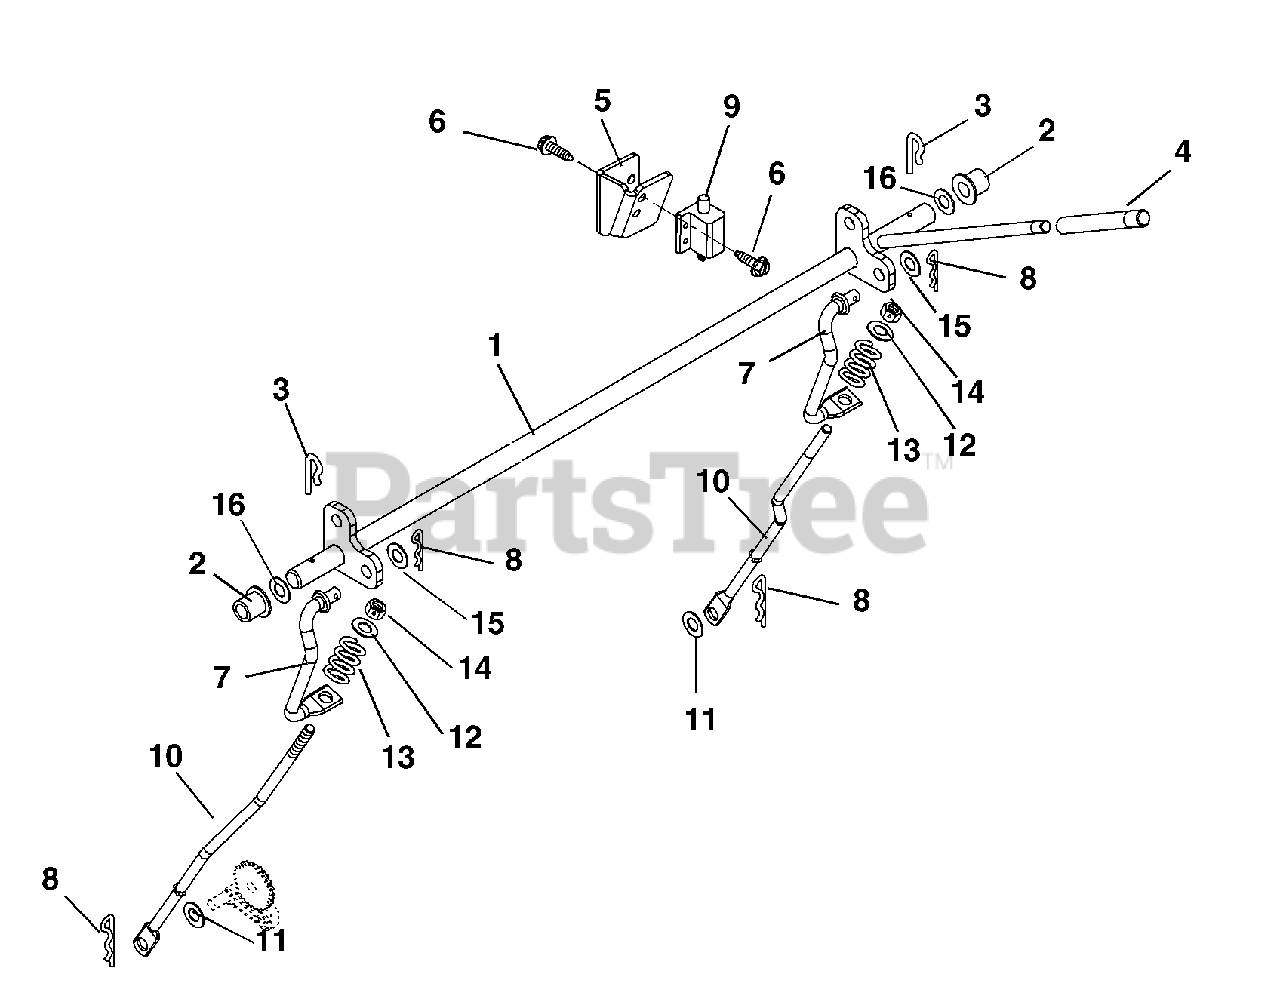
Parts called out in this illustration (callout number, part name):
1	WMT, PARKING BRAKE
2	BSHG-FLG .630X1.000X.625 NY
3	PIN, SPRING CLIP
4	GRIP,HAND CLUTCH LEVER
5	BRACKET, BRAKE SWITCH
6	@SCR-TAP 10-24X.50 HWH TR YWZC
7	ROD-OVER CENTER
8	PIN-HAIR, ENDRIES #25 YWZC
9	SWITCH, INTERLOCK NC
10	ROD-PARK BRAKE EZT
11	WSHR-FL-STL .406X1.00X.188 YWZ
12	@WSHR-FL-STL.344X.688X.065YWZC
13	SG-COMP .063X.53X1.187
14	@NUT-LK-NYL .312-18 YWZC
15	@WSHR-FL-STL.406X.812X.065 YWZ
16	WSHR-FL-STL .627X.990X.032
